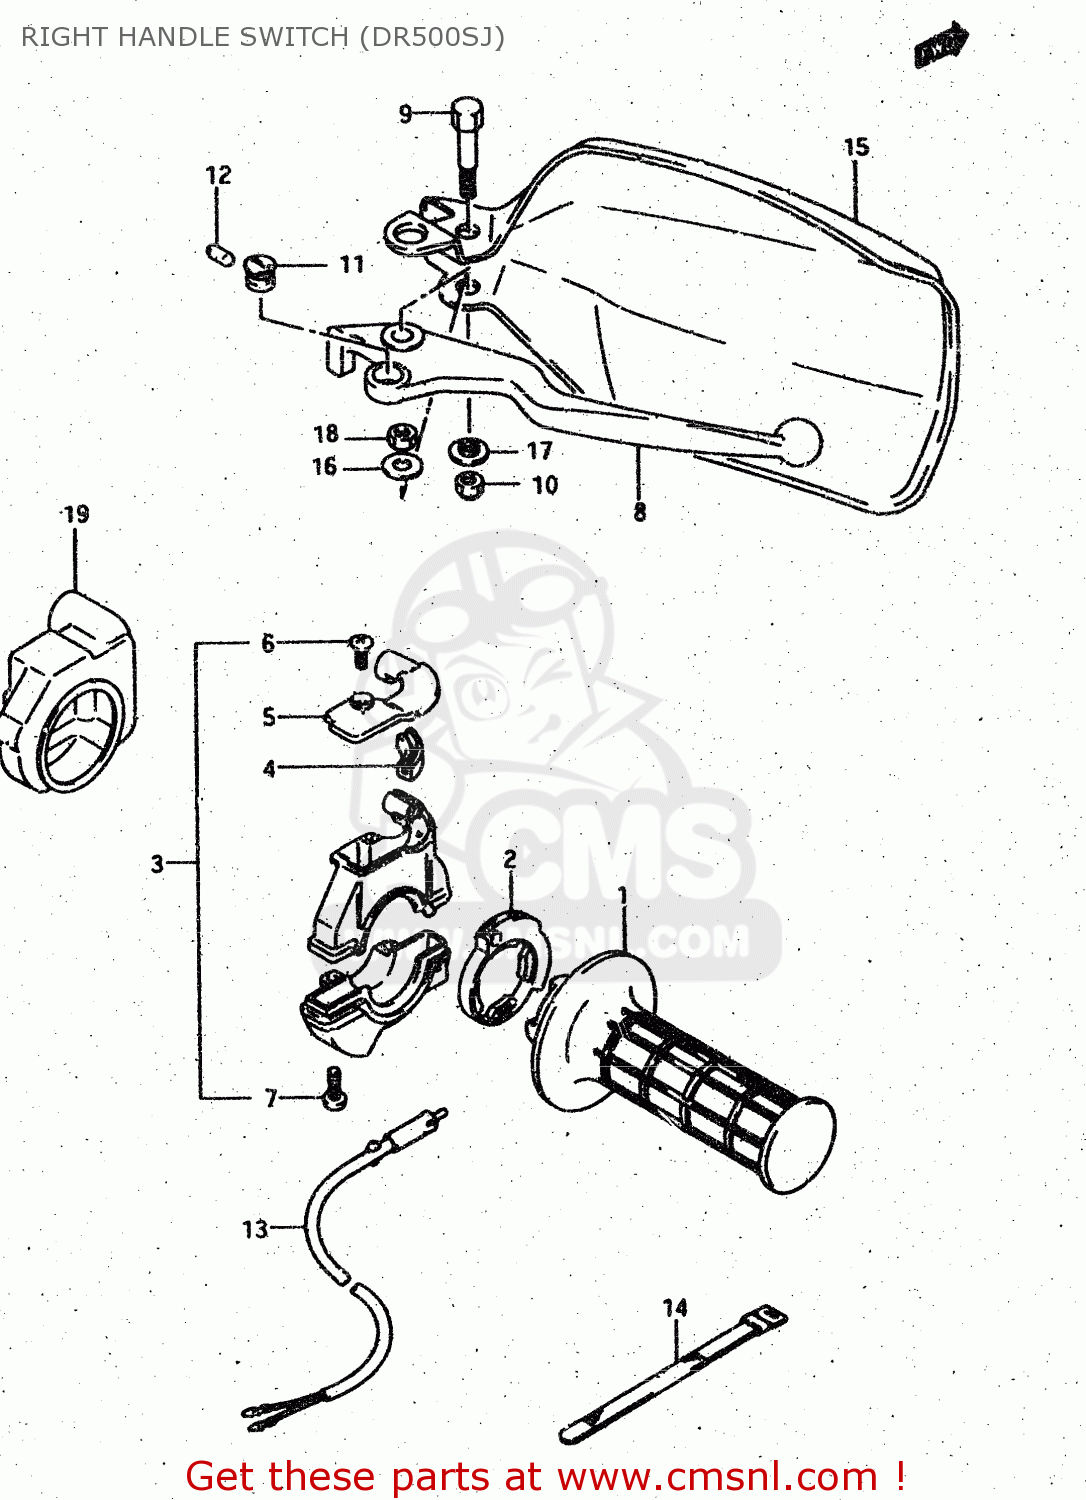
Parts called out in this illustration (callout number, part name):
1	GRIP,THROTTLE
2	ROTOR,THROTTLE GRIP
3	CASE ASSY,THROTTLE
4	GUIDE PIECE,THROTTLE
5	COVER,THROTTLE CASE
6	SCREW
7	SCREW
8	LEVER,BRAKE
9	BOLT,LEVER PIVOT
10	NUT
11	ADJUSTER
12	ROD,PUSH
13	SWITCH ASSY,STOP
14	CLAMP(L:120)
15	COVER,KNUCKLE,
16	WASHER(6.5X16X1.2)
17	WASHER
18	NUT 6MM
19	COVER,THROTTLE CASE
